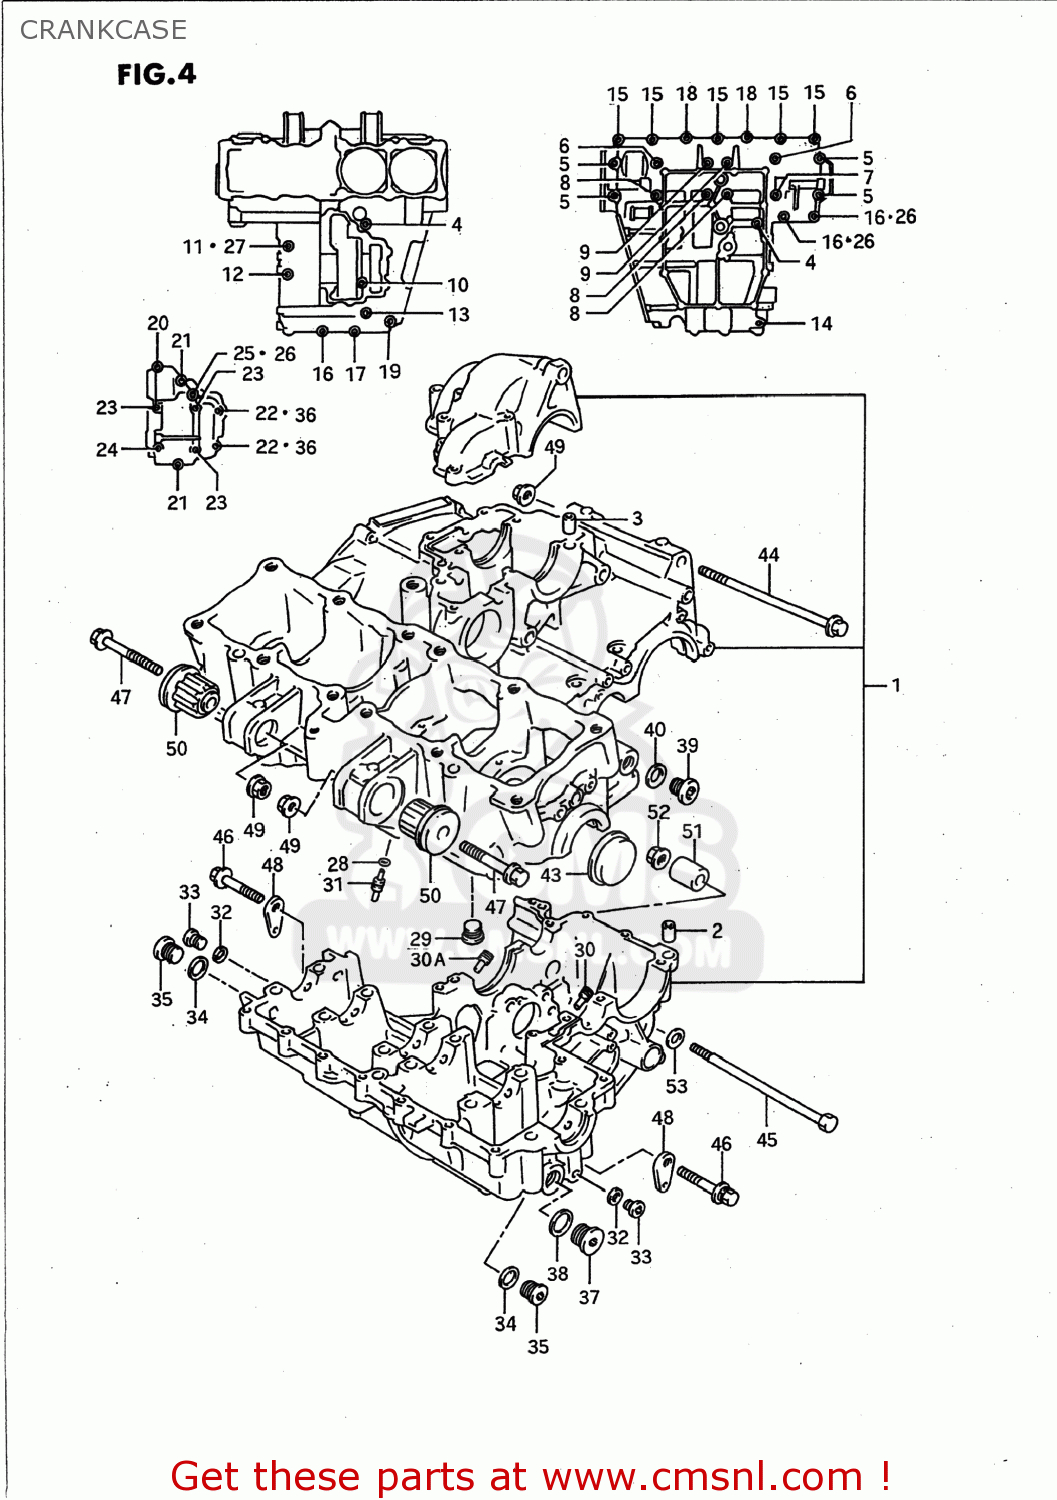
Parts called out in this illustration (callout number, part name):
1	CRANKCASE SET
2	PIN(10.4X13X22)
3	PIN
4	BOLT(6X105)
5	BOLT 9X80
6	BOLT(9X95)
7	BOLT(9X105)
8	BOLT(9X115)
9	BOLT(9X60)
10	BOLT
11	BOLT
12	BOLT
13	BOLT
14	BOLT
15	BOLT
16	BOLT
17	BOLT
18	BOLT
19	BOLT
20	BOLT
21	BOLT
22	BOLT
23	BOLT
24	BOLT
25	BOLT(6X145)
26	GASKET(6.2X13X1.2) (NAS)
27	GASKET(8.2X14X1) (NAS)
28	O RING(D:1.2,ID:4)
29	PLUG,CRANKCASE,UPPER
30	JET
30A	JET(140)
31	JET,OIL GALLERY
32	GASKET(10X14X3.6) (NAS)
33	PLUG(10X6.8)
34	GASKET(16X22X2) (NAS)
35	PLUG
36	GASKET(5.8X11X1.2) (NAS)
37	PLUG(22X11)
38	GASKET(22X27X2) (NAS)
39	PLUG
40	GASKET(13.8X18.8X4.8) (NAS)
41	BEARING,CRANK THRUST(GREEN)
42	BEARING,CRANK THRUST(RED)
43	PLUG
44	BOLT 10X150
45	BOLT,ENGINE MOUNTING,REAR,LOWER
46	BOLT
47	BOLT
48	NUT,ENGINE MOUNT,LOWER
49	NUT
50	BUSH,ENGINE MOUNTING
51	SPACER,ENGINE MOUNT
52	NUT 12MM
53	WASHER
